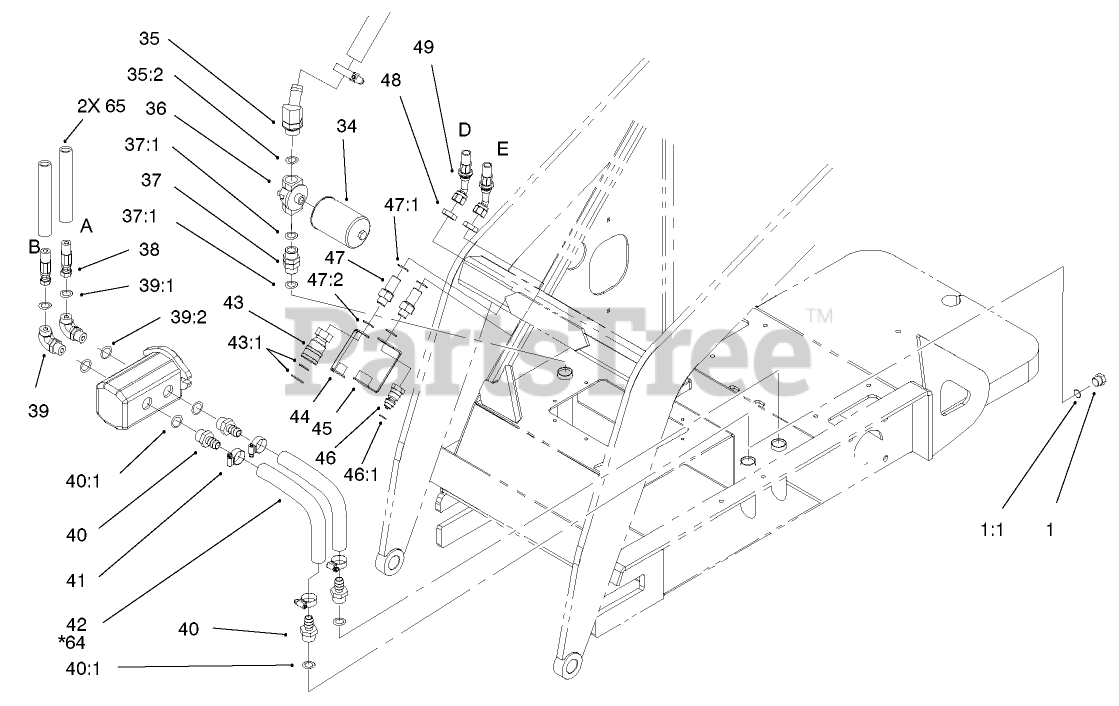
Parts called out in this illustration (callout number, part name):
1	PLUG-HEX
1:1	O-RING
34	FILTER-OIL, TRANSMISSION
35	ELBOW-45 DEG
35:2	O-RING
36	HEAD-FILTER
37	FITTING-THREAD, STRAIGHT
37:1	O-RING
38	HOSE-HYD
39	FITTING-ELBOW 90
39:1	O-RING
39:2	O-RING
40	FITTING-STRAIGHT
40:1	O-RING
41	CLAMP-HOSE
42	HOSE-SUCTION, HYD
43	COUPLER-FACE, FLUSH
43:1	KIT-SEAL
44	CAP-DUST, COUPLER
45	CAP-DUST, NIPPLE
46	NIPPLE-FACE, FLUSH
46:1	SEAL KIT
47	FITTING-ADAPTER, BULKHEAD
47:1	O-RING
47:2	O-RING
48	NUT-LOCK, BULKHEAD
49	HOSE-HYD
64	Spring-Compression
65	SLEEVE-GUARD, HOSE
